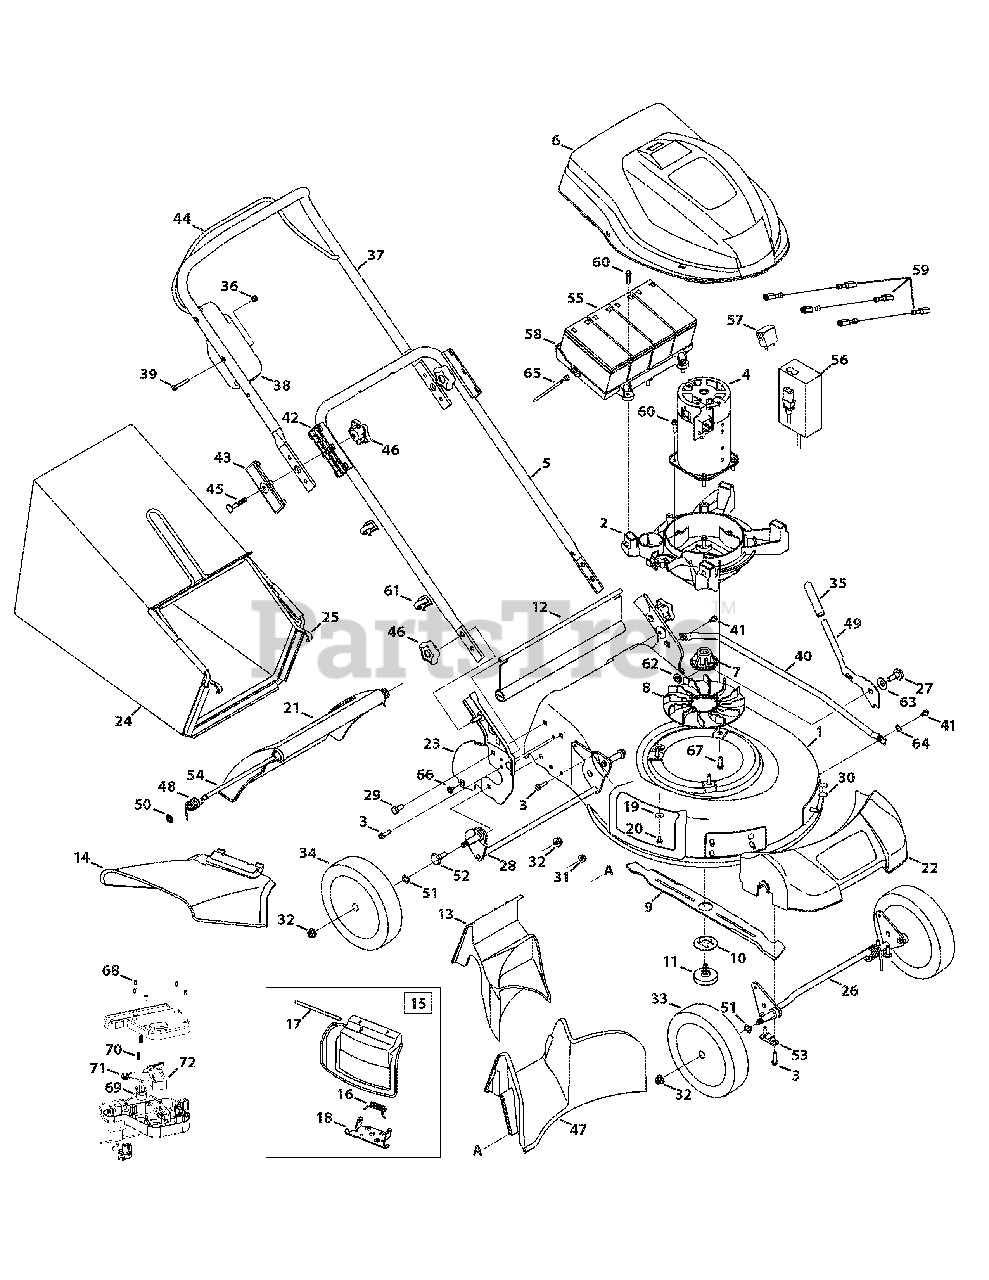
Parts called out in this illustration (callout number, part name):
2	Motor Bracket
3	Screw, 1/4-15 x 1.000
6	Battery Shroud
8	Electric Fan
9	Mulching Blade
10	Blade Locking Plate
11	Blade Bolt Assembly
12	Trail Shield
13	Rear Mulch Plug
14	Side Discharge Chute
15	Mulch Plug
16	Torsion Spring
18	Chute Deflector Adapter
19	Bellville Washer
22	Front Cover
23	Handle Bracket - RH
23	Handle Bracket - LH
25	Grass Bag Frame
26	Front Bracket Assembly
27	Screw, Shoulder, .50 x .66
28	Rear Bracket Assembly
29	Hhcs, 5/16-18 x .625
30	Screw, 5/16-14 x .750
31	Nut, Flange Lock, 5/16-18
32	Nut, Flange Lock, 3/8-16
33	Front Wheel
34	Rear Wheel
35	Foam Grip
36	Nut, Hex Lock, 1/4-20
37	Upper Handle
38	Switch Assembly
39	Screw, Flat, 1/4-20 x 1.75
40	?Cross Bracket
41	Screw, Shldr., 1/4-20 x .50
42	?Lower Handle Insulator
43	Upper Handle Insulator
44	Motor/Blade Control Handle
45	Bolt Carriage, 5/16-18 x 2.50
47	Rear Baffle
48	Door Torsion Spring - RH
48	Door Torsion Spring - LH
49	?Spring Lever
50	Nut, Speed
51	Washer, Wave, .510 x .750 x .017
52	Screw, Shoulder, .500 Dia. X .434
53	Bushing, Block, .505 Dia. X .62
54	?Rear Door Pivot Rod
55	Battery, 12V
56	Battery Charger
57	Battery Level Indicator
58	Battery Tray
59	Battery Jumper
60	Screw, 1/4-15 x .750
61	Cable Guide
62	Spacer, .515 x 1.00 x .310 Lg.
63	Washer, Bell, .510 x 1.14 x .040
64	Washer, Wave, .385 x .598
65	?Cable Tie
66	Screw, #10-16 x .500
67	Screw, 5/16-12 x .750
68	Screw, 10-9 x .50
69	Bail Lock Button
70	Compression Spring, .260 x .687
71	Torsion Spring
72	?Switch Button
